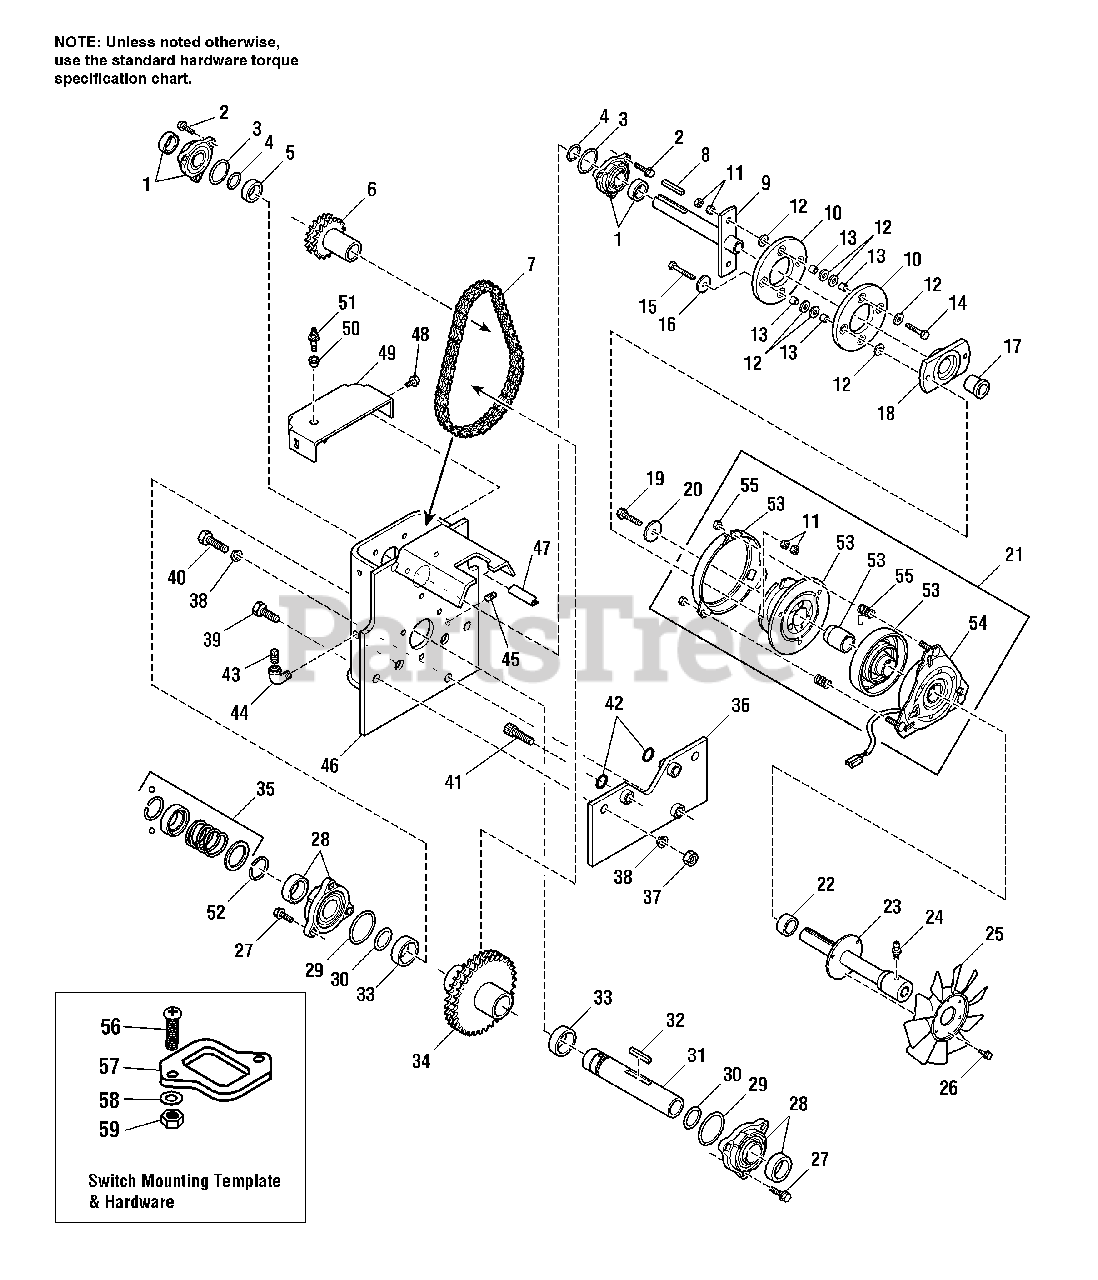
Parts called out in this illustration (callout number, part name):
1	BEARING, Flange
2	CAPSCREW, Hex Washer Hd, Taptite, 5/16-18 X 1
3	O-RING, 1.610 ID
4	O-RING, .989 ID
6	SPROCKET ASSEMBLY, 19 Tooth
7	CHAIN, Roller, #40-2 x 46 Pitches
9	SHAFT & BAR ASSEMBLY
10	COUPLING, Flex
11	NUT, Hex Lock, 5/16-18
12	WASHER, 5/16
14	CAPSCREW, Hex Hd, 5/16-18 x 1-1/4
15	CAPSCREW, Hex Head 5/16-18 x 2 G5
16	WASHER, 5/16
18	HUB ASSEMBLY
19	CAPSCREW, Hex Hd, 3/8-16 x 1-3/8
20	Washer, 3/8
21	CLUTCH ASSEMBLY, Electric
23	SHAFT ASSEMBLY
24	FITTING, Grease, 1/4
26	CAPSCREW, Hex Washer Hd, Taptite, #10-24 x 1/2
27	CAPSCREW, Hex Washer Hd, Taptite, 3/8-16 x 1
28	BEARING, Flange
29	O-RING, 2.238
30	O-RING, 1.372 ID
32	Key, 1/4 x 1/4 x 1-1/2
34	SPROCKET ASSEMBLY, 34 Tooth
35	KIT, Spring Lock
36	PLATE ASSEMBLY
37	NUT, Hex, 1/2-13
38	WASHER, Lock, 1/2
39	CAPSCREW, Hex Hd, 1/2-13 x 1-1/4
40	CAPSCREW, Hex Hd, 1/2-13 x 1-3/4
41	CAPSCREW, Hex Socket, 1/2-13 x 1-3/4
43	PLUG, Pipe, 3/8 NPT
44	FITTING, Elbow, 3/8 NPT
45	PLUG, Pipe Square Hd, 1/4 NPT
46	CASE ASSEMBLY
48	CAPSCREW, Hex Washer Hd, Taptite, 5/16-18 x 1/2
49	COVER ASSEMBLY
50	BUSHING, Rubber
51	BREATHER ASSEMBLY
52	RETAINING RING
53	KIT, Rotor and Armature
54	FIELD ASSEMBLY, Electric Clutch
55	KIT, Spring and Nut
56	CAPSCREW, Truss Hd, #10-32 x 1/2
57	TEMPLATE, Switch Mounting
58	WASHER, 3/16
59	NUT, Hex Lock, #10-32
